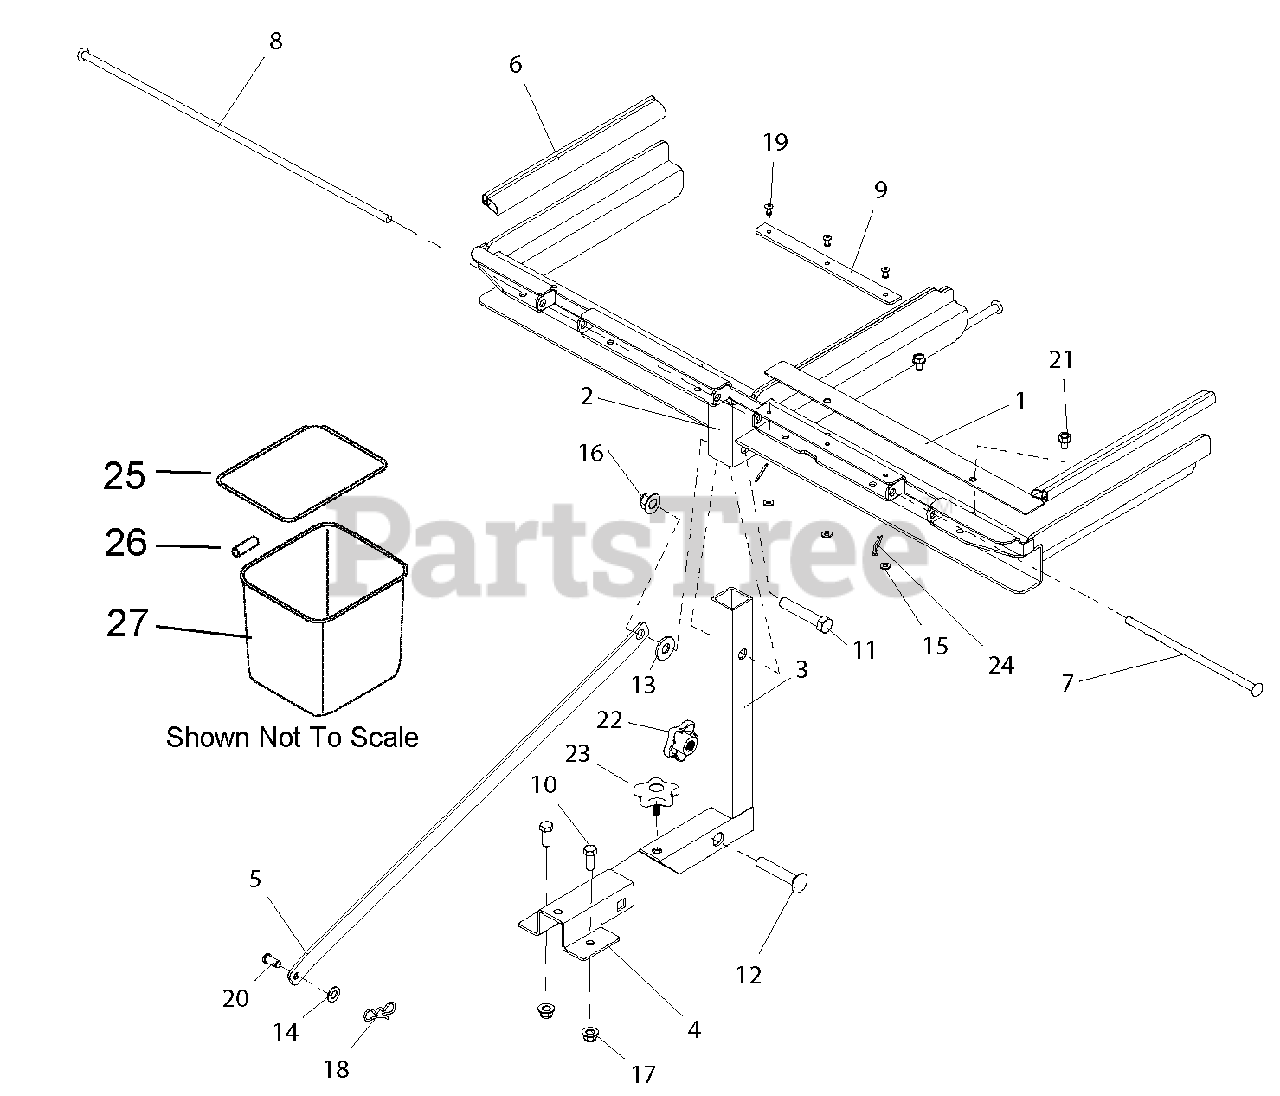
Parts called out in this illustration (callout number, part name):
1	OVERLAP PLATE, BAGGER FRAME
2	ASM, BAGGER FRAME UPPER
3	BRKT, RECEIVER SLEEVE INSERT
4	BRKT, RECEIVER LOWER
5	BRKT, BAG FRAME SUPPORT BAR
6	SEAL, BULB
7	PIN, BAGGER HINGE (L)
8	PIN, BAGGER HINGE (R)
9	SEAL, HINGE
10	BOLT-HEX-Gr5-UNC-YWZC
11	BOLT-HEX-Gr5-UNC-YWZC
12	BLT-RDHDSQNK .50-13X2.75 G5 Y
13	WSHR-FL-STL .531X1.250X.100 YWZC
14	WSHR-FL-STL.406X.812X.065 YWZ
15	WSHR-FL-STL.219X.500X.049YWZC
16	NUT-LK-NYL-FLG .50-13 YWZC
17	NUT-LK-NYL-FLG .38-16 YWZC
18	PIN, BOWTIE LOCKING .091X1.875
19	RVT-POP .187x.375
20	PIN-CLEV .38X.75 YWZC
21	SCR-TAP .31-18X.50 HWH TR YWZ
22	KNOB, WING
23	KNOB, WING STUDDED
24	PIN-HAIR, ENDRIES #25 YWZC
25	Frame, Zoom Bag
26	Tube, .38 .50 x 3.00
27	Bag, Mesh Zoom
